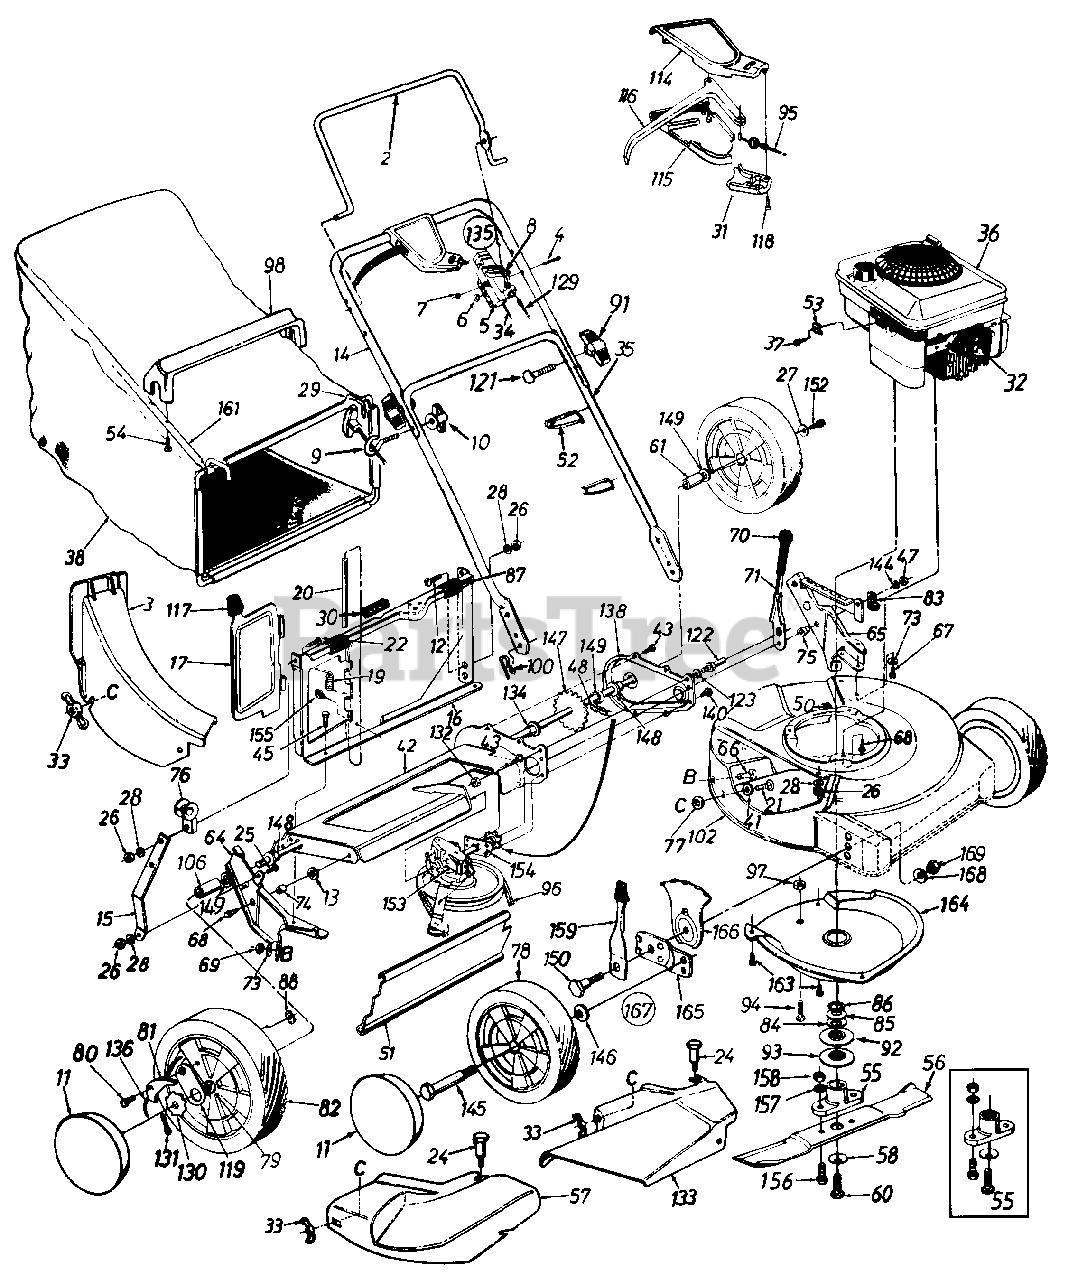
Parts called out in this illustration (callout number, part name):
3	Rear Discharge Chute Ass'y.
4	Oval C-Sunk Scr.
5	Throttle Body
6	Spr. Wash. .66" I.D.
7	Hex L-Nut 1/4-20 Thd.
8	Throttle Lever
9	Rope Guide
10	Wing Nut 1/4-20 Thd.
11	Hub Cap
12	Truss Mach. Scr. 1/4-20 x .62"
13	Fl-Wash. .383" I.D. x 1" O.D.
20	Pivot Pin
21	Carriage Bolt 1/4-20 x .62"
22	Truss Mach. Scr. 1/4-20 x 3/4"
24	Shoulder Bolt .312 Dia. x .18 Lg. - Special
25	Hex Bolt 1/4-20 x .62" Lg.
26	Hex Nut 1/4-20 Thd.
27	Bell-Wash. 1/4" I.D.
28	L-Wash. 1/4" I.D.
30	Foam Strip
31	S.P. Control Cover
32	Spark Plug Insulator
33	Wing Nut w/Washer
34	Throttle Control Wire 61"
36	Engine
37	Hex Self-Tap Scr. #10-32 x .62"
38	Grass Bag
41	Fl-Wash. .344" I.D. x .62"
45	Hex AB-Tap Scr. 1/4 x .62"
47	Hex Patch L-Nut 3/8-24 Thd.
48	#48 Chain .500" Pitch x 30 Links
51	Rear Flap
52	Cable Tie
53	Cable Clamp
54	Hex AB Scr. #12 x 1.25" Lg.
55	Blade Adapter Kit
56	21" Mulching Blade
57	Mulching Plug
58	Bell-Wash. .39" I.D.
60	Hex Bolt 3/8-24 x 1.5" Lg. (Grade 5)
61	Spacer .513" I.D. x .703" O.D. x .69" Lg.
67	Hex Wash. Hd. B-Tap Scr. 5/16-18
68	Hex Was. Hd. TT-Tap Scr. 3/8-16
69	Hex Nut 5/16-18 Thd.
71	Height Adj. Lever
73	Bell-Wash. 5/16" I.D.
74	Spacer
75	Shld. Spacer .500" Dia.
76	Rope Guide
77	Bolt Retainer 1/4 x .50" O.D.
78	Front Wheel Ass'y. Comp.
79	Bearing 1/2" I.D.
80	Shld. Scr. .342" Dia. x .268
81	Pawl
82	Rear Wheel Ass'y. Comp.
83	Clamp
84	Fl-Wash. .88" I.D.
85	Spr-Washer .89" I.D.
86	Crankshaft Spacer
87	Panel Clip
88	Weld L-Nut 1/4-20 Thd.
91	Hand Knob
92	Pulley Half - Upper
93	Pulley Half - Lower
94	Phil. Mach. Scr. 1/4-20
95	S.P. Cable
96	"V"-Belt
97	Sems Nut 1/4-20 Thd.
98	Bag Handle
100	Hairpin Clip
114	Self-Propelled Control Cover
115	Self-Propelled Control Cover
116	Control Lever
117	Door Grip
118	Fl - "C"-Sunk Hd. Tap Scr. #10 x .75" Lg.
119	Pawl Plate
121	Curved Carr. Bolt 5/16-18 x 2" Lg.
122	Shld. Pin 3/8-24 x 1.43" Lg.
123	L-Wash. 3/8" I.D.
129	Control Cable 47" Lg.
130	Ratchet Wheel 1.62" O.D.
131	Cotter Pin 1/8" Dia. x 1.00" Lg.
132	Hex Jam Nut 3/8-24 Thd.
133	Side Chute Deflector Ass'y.
134	Hex Flange Bearing
135	Throttle Box Comp.
136	Spring - Nylon
144	Fl-Wash. .385" I.D. x .87"
145	Axle Bolt
146	Bell-Wash. .4" I.D. x .88" O.D.
147	Rear Shaft Ass'y. 21.94" Lg.
148	Hex Flange Bearing .506" I.D. Plastic
149	Fl-Wash. .531" I.D. x .930"
150	Shld. Bolt .5" Dia. x .434"
152	Hex Bolt 1/4-20 x .62" Lg. (Grade 5)
153	Transmission Comp. (See Breakdown)
155	Hex B-Tap Scr. #10 x .38
156	Hex Scr. 3/8-24 x 1.0" Lg.
157	L-Wash. 3/8" I.D.
158	Hex Nut 3/8-24 Thd.
159	Spring Lever Ass'y. w/knob
163	Hex Wash. Hd. Tap Scr. 1/4 x .38" Lg.
166	Height Adj. Plate
167	Front Height Adj. Ass'y. Comp. - R.H.
168	Bell-Wash. .39" I.D. x 1.38" O.D.
169	Hex Nut 3/8-16 Thd.
